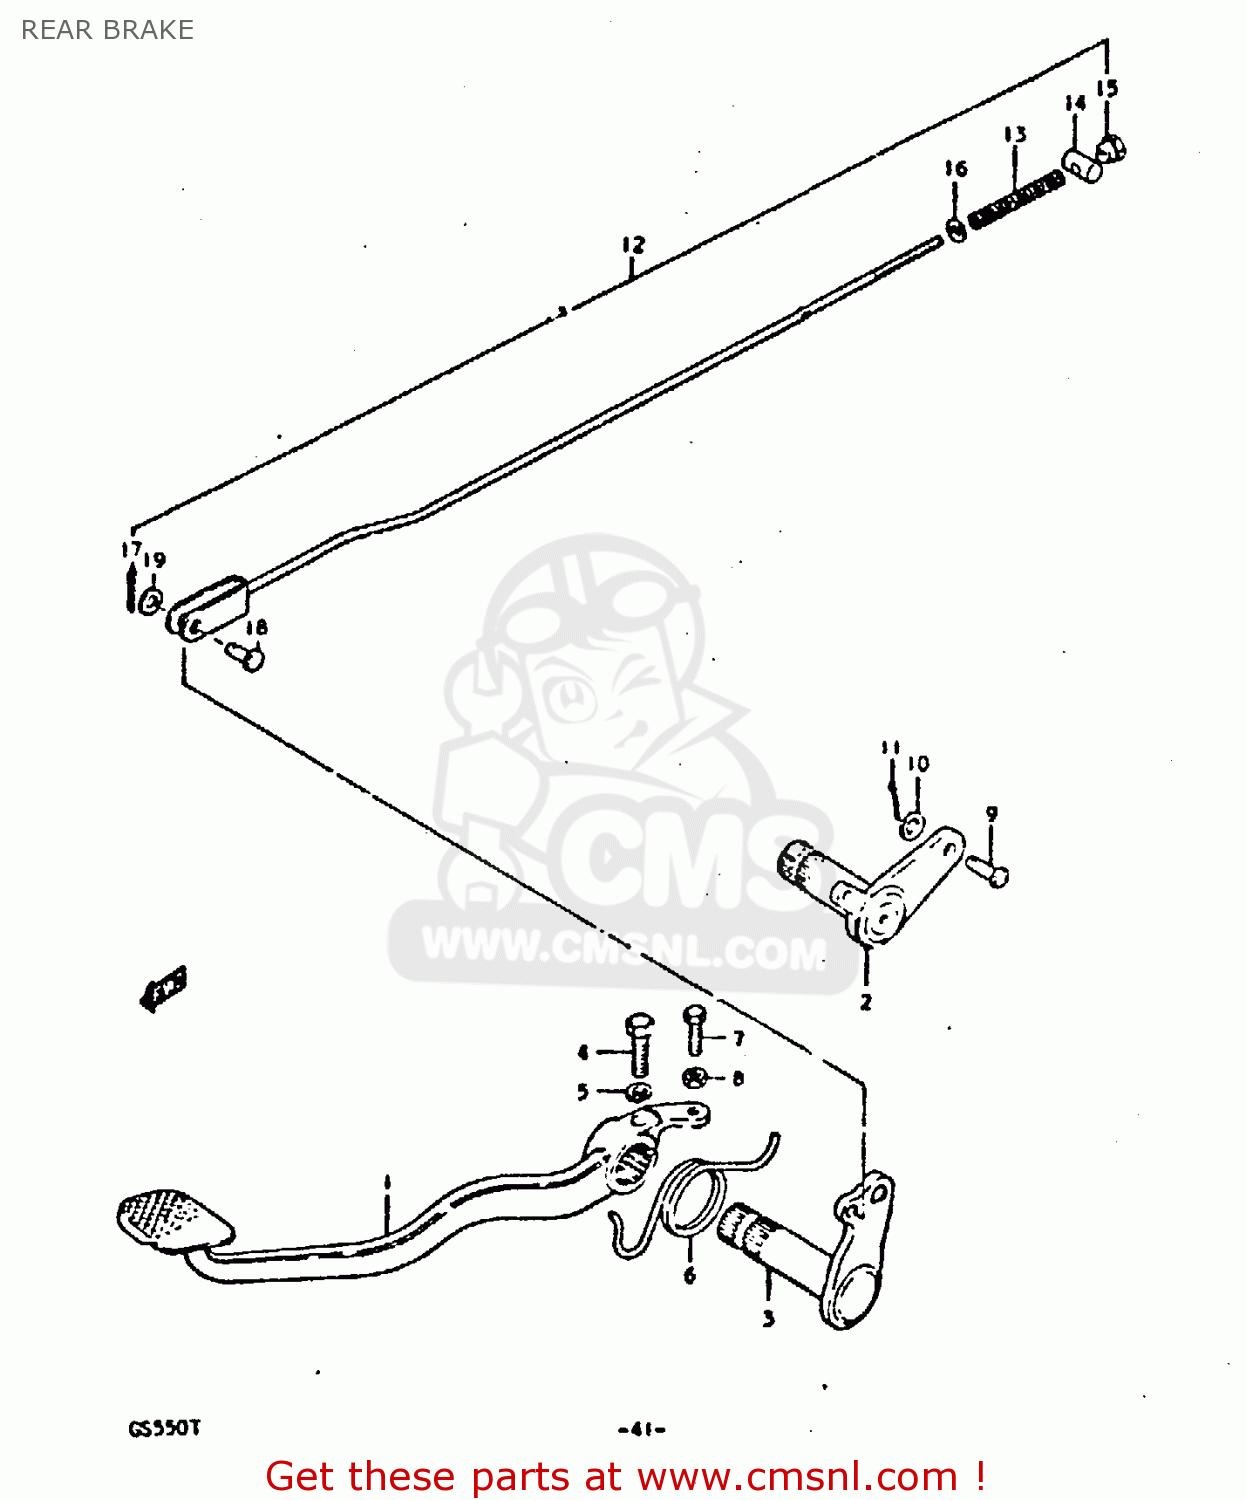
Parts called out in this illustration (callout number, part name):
1	PEDAL,BRAKE
2	ARM,BRAKE PEDAL ROD
3	ARM,BRAKE PEDAL
4	BOLT
5	LOCK WASHER
6	SPRING
7	BOLT
8	NUT
9	PIN
10	WASHER
11	PIN
12	ROD ASSEMBLY,REAR BRAKE
13	SPRING
14	PIN
15	NUT
16	WASHER
17	PIN 20X20
18	PIN(L:13.5)
19	WASHER
